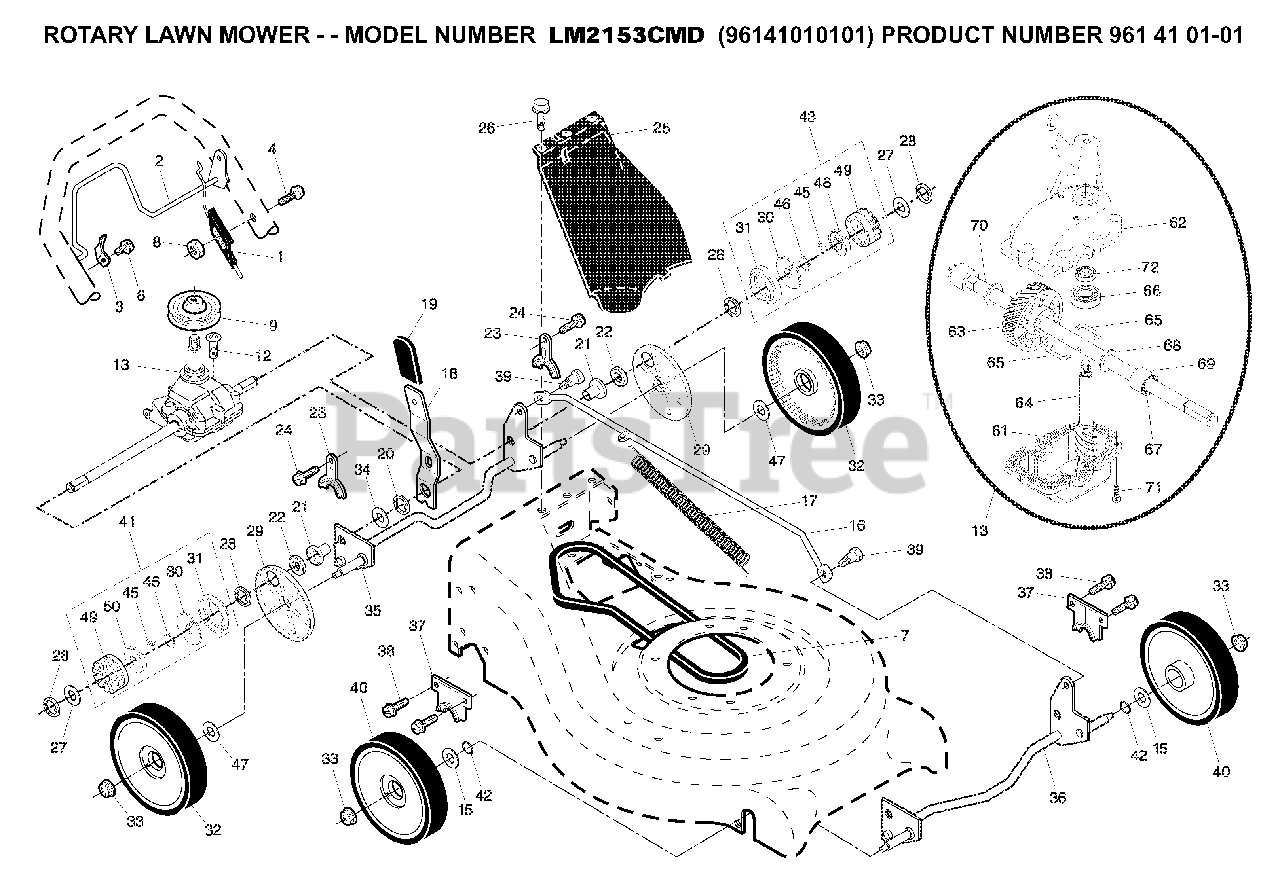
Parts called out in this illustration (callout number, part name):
2	BAIL.CONT.DR.21.RWGD.BLACK
3	DOWNSTOP BRACKET
7	V-BELT
8	NUT.HEX.FLANGE.1/4
13	TRANSMISSION.21.RWGD
15	WASHER PM
16	ROD.CONNECTING.SPT.BLACK
17	SPRING EXTENSION
18	SPRING.SELECTOR.SPT.21
19	KNOB, SELECTOR SPRING
21	RP BEARING SUPPORT
22	BEARING, BALL
23	BRACKET
27	WASHER
28	E-RING 7/16 RE
29	COVER.DUST.WHEEL
30	DISC.DRIVE.21.EZ-WALK
31	SEAL.PINION
33	NUT.HEX.FLANGE.3/8-16.LOCKNUT
35	SHAFT ASSY REAR
36	SHAFT ASSY, FRONT
37	RETAINER.FRONT.SHAFT
39	SHOULDER BOLT SEMI GIMLET PT.
41	PINION ASSY, RH
42	O-RING..070X.487.NEOPRENE
43	PINION ASSY, LH
45	PAWL.DRIVE.21.EZ-WALK
46	SPRING, TORSION
47	WASHER FLUT
48	RETAINER.DRIVE.21.EZ-WALK.LT
49	GEAR, PINION
50	RETAINER, DRIVE, RH
61	CASE, LOWER
62	CASE, UPPER
63	GEAR.24.TOOTH.WALK.MOWER
64	SHAFT INPUT
65	WIRE, FORMED
67	SEAL.OUTPUT.SHAFT
70	SHAFT.OUTPUT.RGD.VS/EZ
72	SEAL INPUT SHAFT
